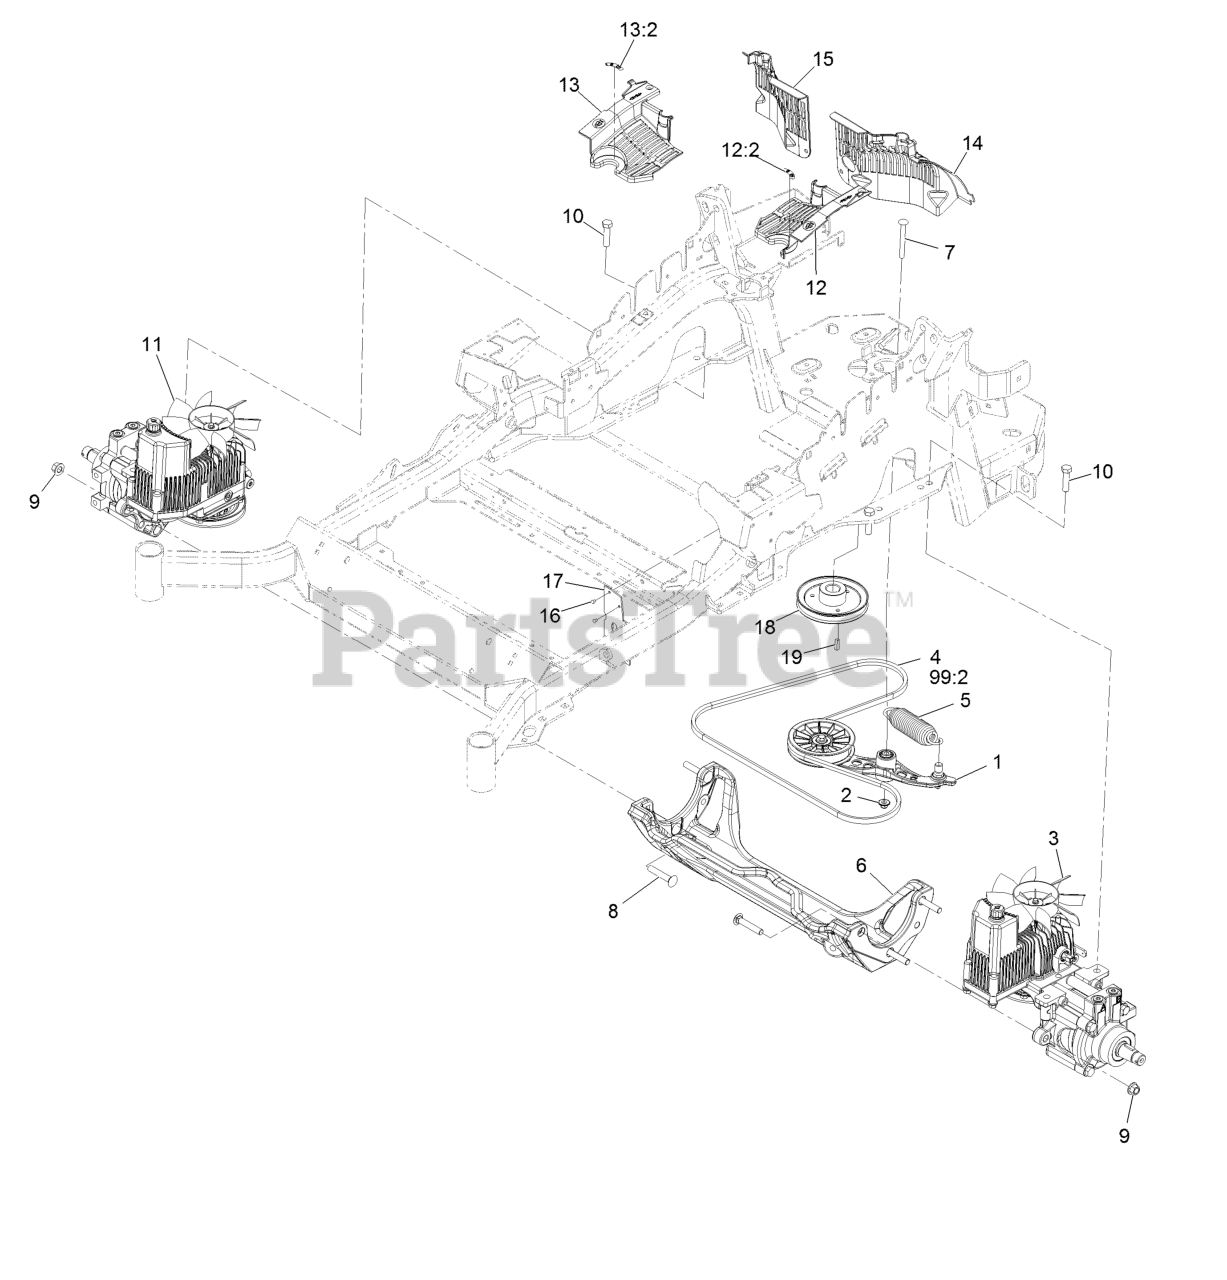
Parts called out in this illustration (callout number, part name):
1	Pump Idler ASM
2	Nut-Nyloc 3/8-16 Flg
3	LH Hydro ASM (12Cc W/ Shock)
4	Belt
5	Spring-Extension
6	Cradle-Hydro
7	Bolt-Carriage Shoulder 3/8-16 X 3 1/2
8	Screw-CARR
9	Nut-Lock 1/2-13
10	Screw-HH 1/2-13 X 1 1/4
11	RH Hydro ASM (12Cc W/ Shock)
12	LH Hydro Guard ASM
12:2	Decal-Oil, Hydro
13	RH Hydro Guard ASM
13:2	Decal-Oil, Hydro
14	Guard-Hydro, Rear (LH)
15	Guard-Hydro, Rear (RH)
16	Rivet 3/16 X 1/4
17	Deflector-Air Flow
18	Sheave
19	Key-Machine 1/4 X 1/4 X 1
99	Bottle-Oil, 32Oz Hydraulic
99	Filter-Hydro
99	Bottle,Oil 1 Gallon Hydraulic
99	Kit, Hydro Service
99:1	Bottle-Oil, 32Oz Hydraulic
99:2	Belt
99:3	Filter-Hydro
